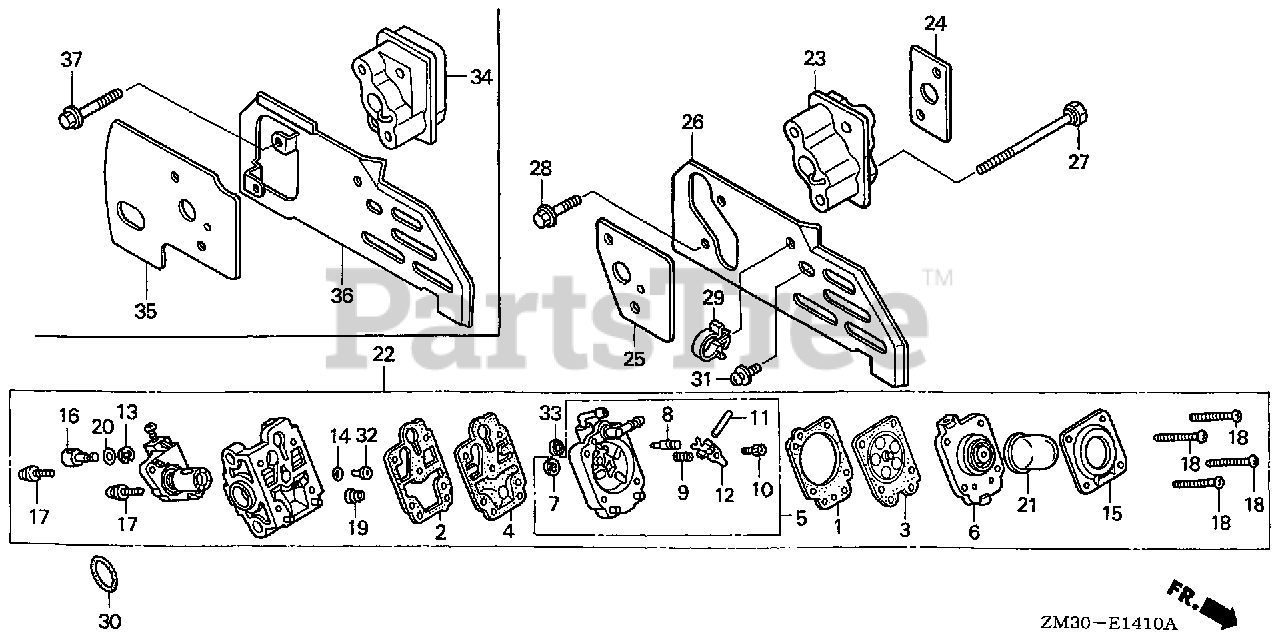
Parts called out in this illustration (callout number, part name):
1	GASKET, METERING DIAPHRAGM
2	GASKET, PUMP
3	DIAPHRAGM ASSY., METERING
4	DIAPHRAGM, PUMP
5	BODY ASSY., PUMP (CARBURETOR NO.)
6	BODY ASSY., AIR PURGE
7	SCREEN, INLET (CARBURETOR NO.)
8	VALVE, INLET NEEDLE
9	SPRING, METERING LEVER
10	SCREW, METERING LEVER PIN
11	PIN, METERING LEVER
12	LEVER, METERING
13	RING, SPRING RETAINING
15	COVER, PRIMER PUMP
17	SCREW, THROTTLE COLLAR
18	SCREW, PUMP COVER
19	SPRING, PUMP
21	PUMP, PRIMER
22	CARBURETOR ASSY. (WYL 132)
24	GASKET, INSULATOR
27	BOLT, HEX. (5X75)
29	CLIP, WIRE HARNESS
30	O-RING (14.8X2.4)
31	SCREW-WASHER (5X10)
32	JET (#31.5) (CARBURETOR NO.)
32	JET (#32.5) (CARBURETOR NO.)
32	JET (#33.5) (CARBURETOR NO.)
33	FILTER, FUEL INLET (CARBURETOR NO.)
34	INSULATOR, CARBURETOR
35	GASKET, CARBURETOR
36	GUIDE, AIR INLET
37	BOLT, FLANGE (5X32)
